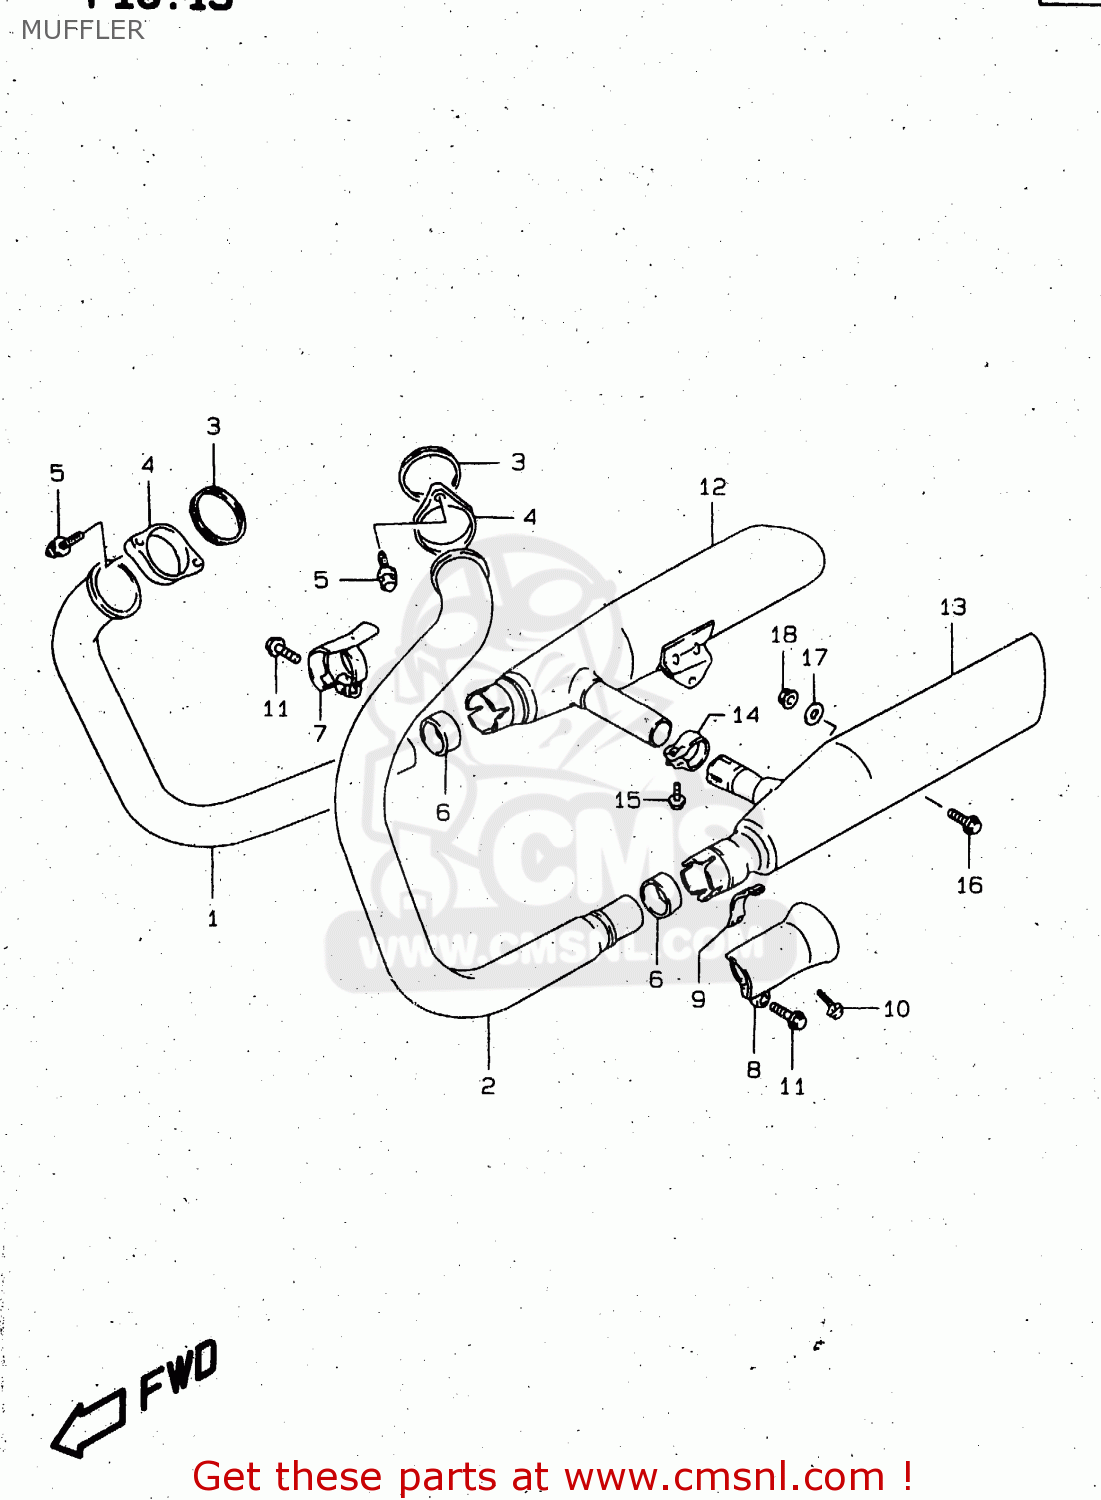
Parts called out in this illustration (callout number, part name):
1	PIPE,EXHAUST R
2	PIPE,EXHAUST,L
3	GASKET,EXHAUST PIPE (NAS)
4	CLAMP,EXHAUST PIPE
5	BOLT(8X35)
6	CONNECTOR,MUFFLER
7	CLAMP,CONNECTOR,R
8	CLAMP,CONNECTOR,L
9	CLAMP,MUFFLER COVER
10	BOLT
11	BOLT(8X35)
12	BODY,MUFFLER,R
13	BODY,MUFFLER,L
14	CLAMP,EXHAUST COUPLER
15	BOLT
16	BOLT
17	WASHER
18	NUT
